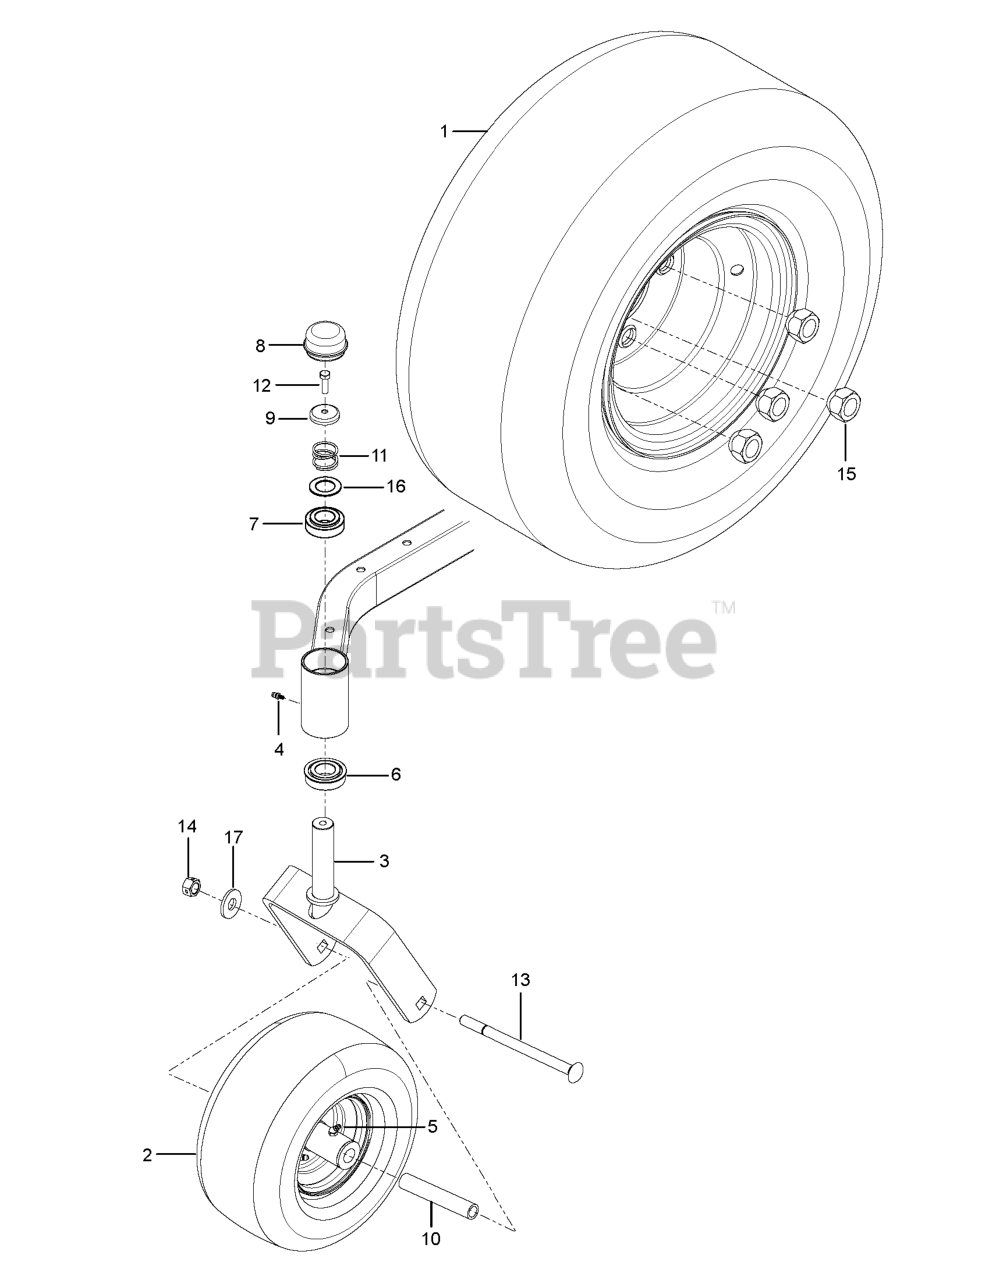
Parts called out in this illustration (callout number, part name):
1	WHEEL CARLSTAR 18X9.5-8" SILVE
2	WHEEL ASSY, WIDE, RZ
3	YOKE.PNT.CASTER.ORG
4	ZERK, 3/16, DRIVE IN
5	ZERK
6	BEARING FLANGED
7	BUSHING, CASTER
8	GREASE CAP
9	CASTER.PLUG
10	SPACER.PIVOT
11	SPRING, CASTER
12	5/16-18X1 HHB G5W/NY
13	RHSNB 1/2-13 X 7.5
14	NUT. 1/2-13 HEX CNTRLK GR 5 ZD
15	LUG NUT 1/2F
16	WASHER, 1.025 ID X 1.64
17	WASHER.9/16 X 1 3/8 X 12 GA.
